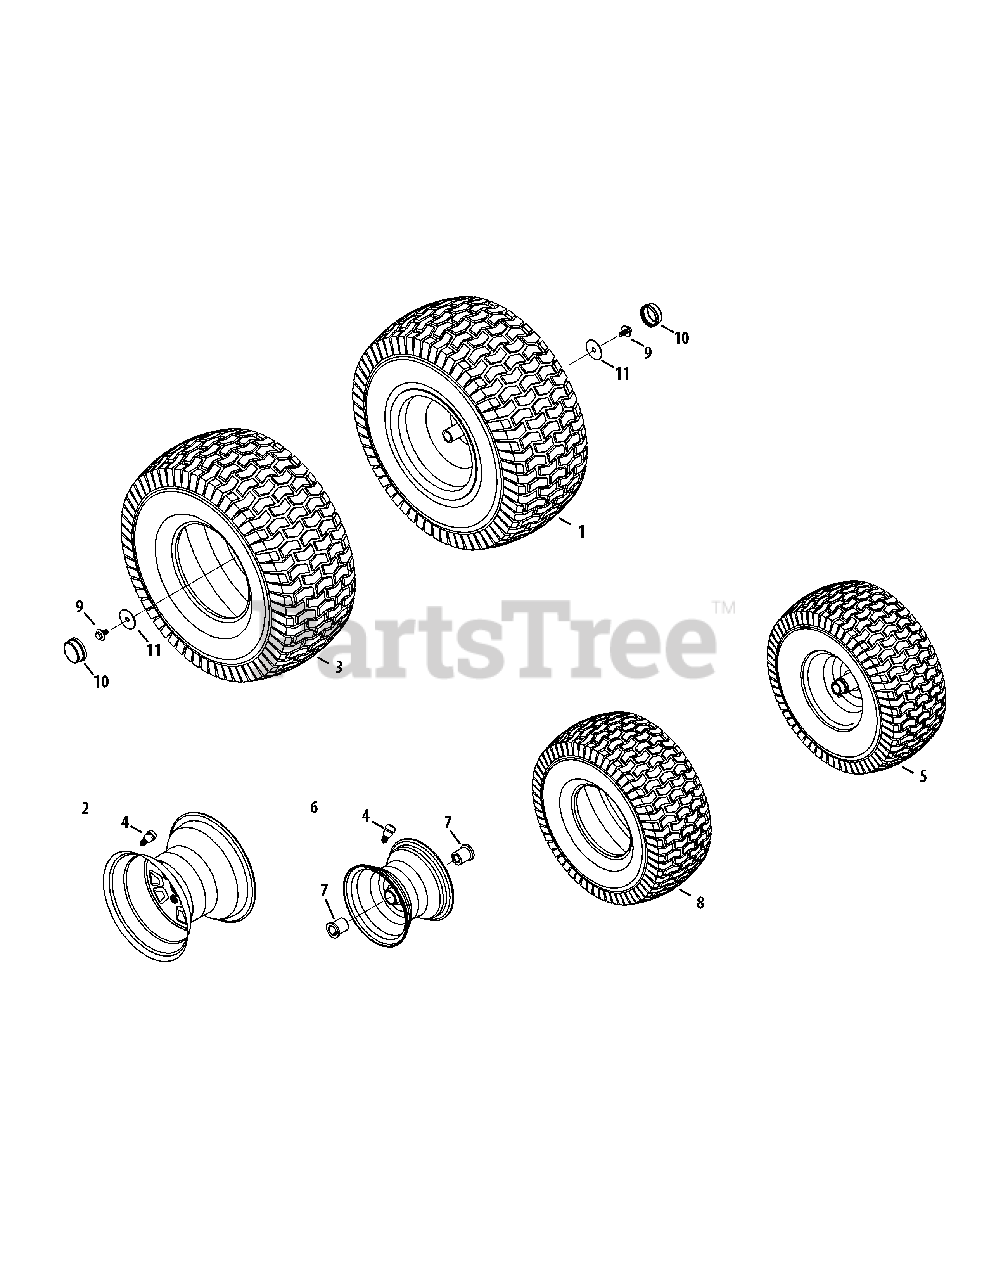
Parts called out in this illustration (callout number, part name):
1	Wheel, Complete, 20 x 8 x 8
2	Rim Ass’y, 8.0 x 7.0 x .750 ID
3	Tire, 20 x 8 x 8 Sq Shoulder
4	Valve, Tubeless Air
5	Wheel, Complete, 15 x 6 x 6
6	Rim Ass’y, 6.0 x 4.5, Flnge Bearings
7	Bearing, Flange, .760 ID
8	Tire, 15 x 6 x 6 Sq Shoulder
9	Screw, 5/16-24 x .850
10	Hub Cap
11	Flat Washer, .350 x 1.59 x .062
